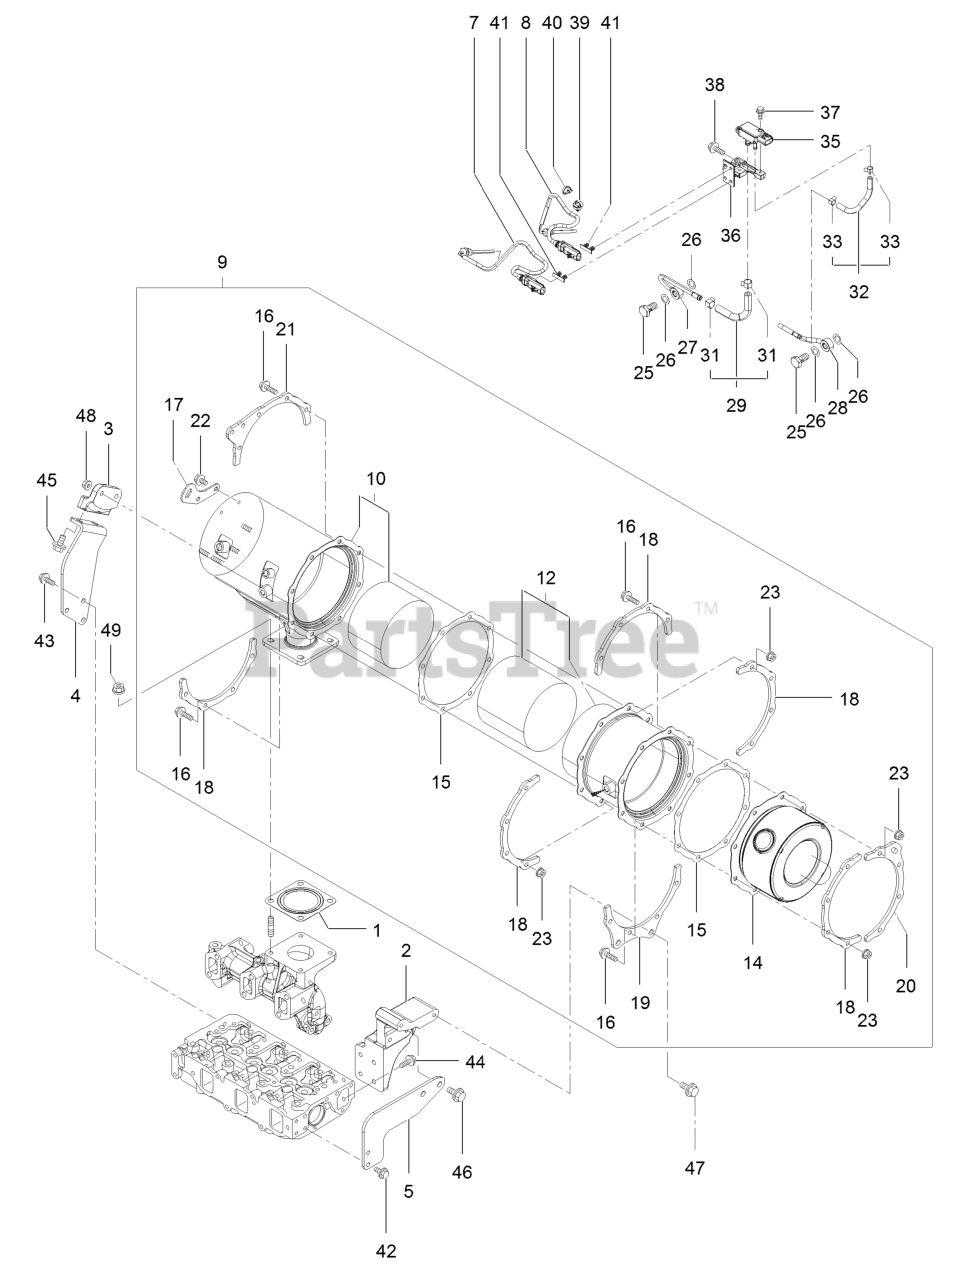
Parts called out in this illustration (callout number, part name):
1	Gasket-Silencer
2	Stay-D P F
3	Stay-D P F
4	Stay-D P F
5	Stay-D P F
7	Sensor-Temp, Exhaust
8	Sensor-Temp, Exhaust
9	D P F ASM
10	Case-D O C
12	Case-Filter, Soot
14	Silencer-D P F
15	Gasket-D P F
17	Lifter-D P F
18	Stiffener-D P F, A
19	Stiffener-D P F, B
20	Stiffener-D P F, C
21	Stiffener-D P F, C
25	Bolt-Joint, Pipe
26	Gasket-Sensor
27	Sensor Pipe ASM
28	Sensor Pipe ASM
29	Exhaust Hose ASM
31	Clip-Hose
32	Exhaust Hose ASM
33	Clip-Hose
35	Sensor-Pressure
36	Bracket-Sensor
39	Band-Clip
41	Clip-Connnector
42	Bolt
43	Bolt
